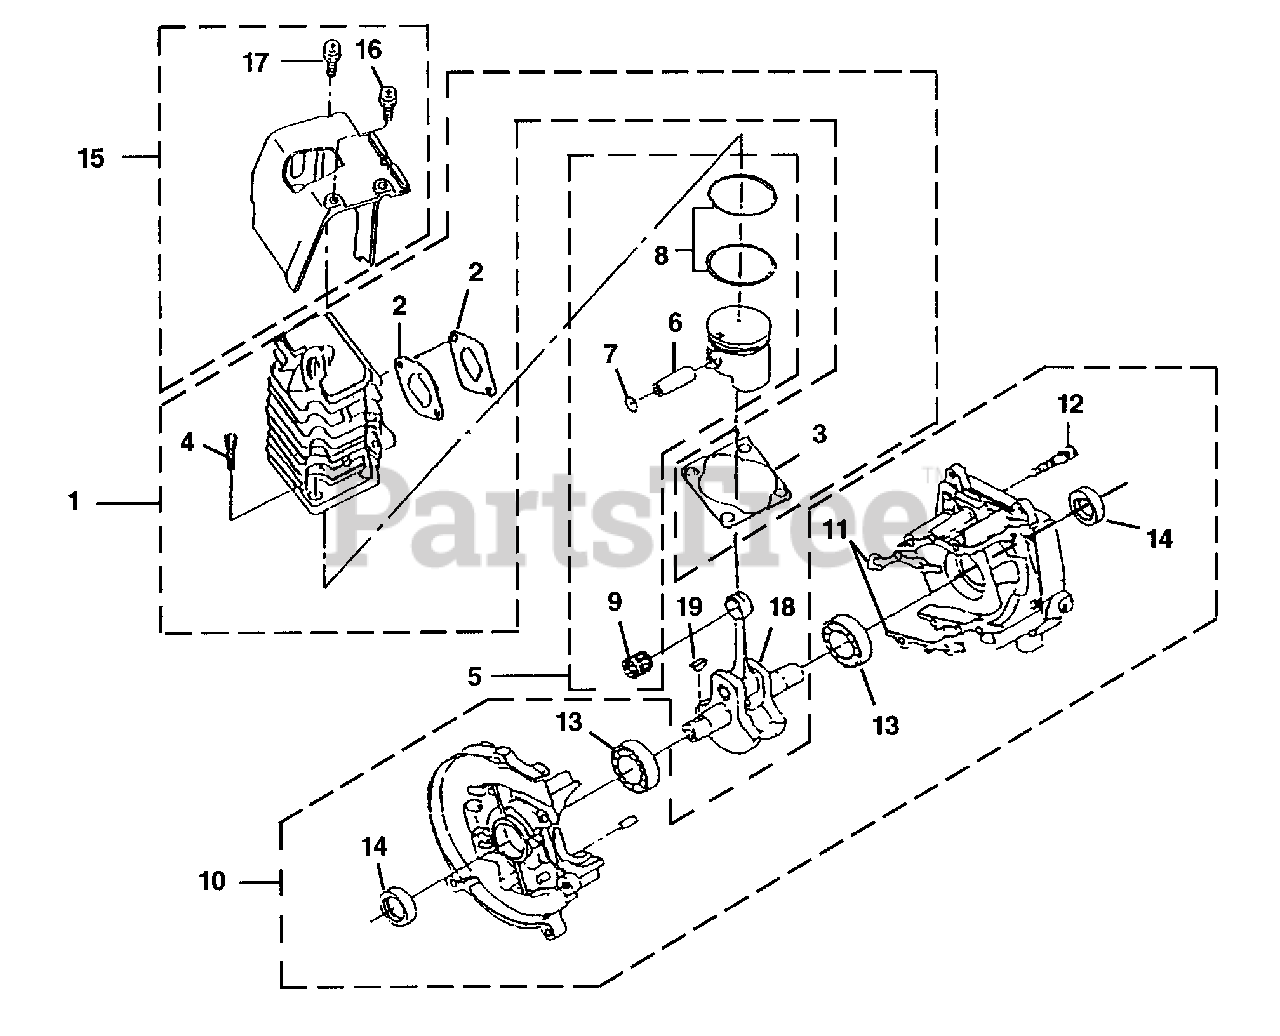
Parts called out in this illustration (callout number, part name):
1	CYLINDER ASSEMBLY
2	GASKET, MUFFLER
3	GASKET-Cylinder
4	SCREW-Socket Hd (M6 X 8)
5	PISTON ASSEMBLY
6	PIN - PISTON
7	RING - Retaining
8	RING - Piston
9	BEARING - Wrist Pin
10	CRANKCASE ASSEMBLY
11	GASKET-Crankcase
12	SCREW-Socket Hd (M5 x 30 SW)
13	BEARING, BALL
14	OIL SEAL
15	CYLINDER COVER
16	SCREW (M5 x 14 W SW)
17	SCREW (M5 X 20W SW)
18	CRANKSHAFT
19	KEY-Woodruff
